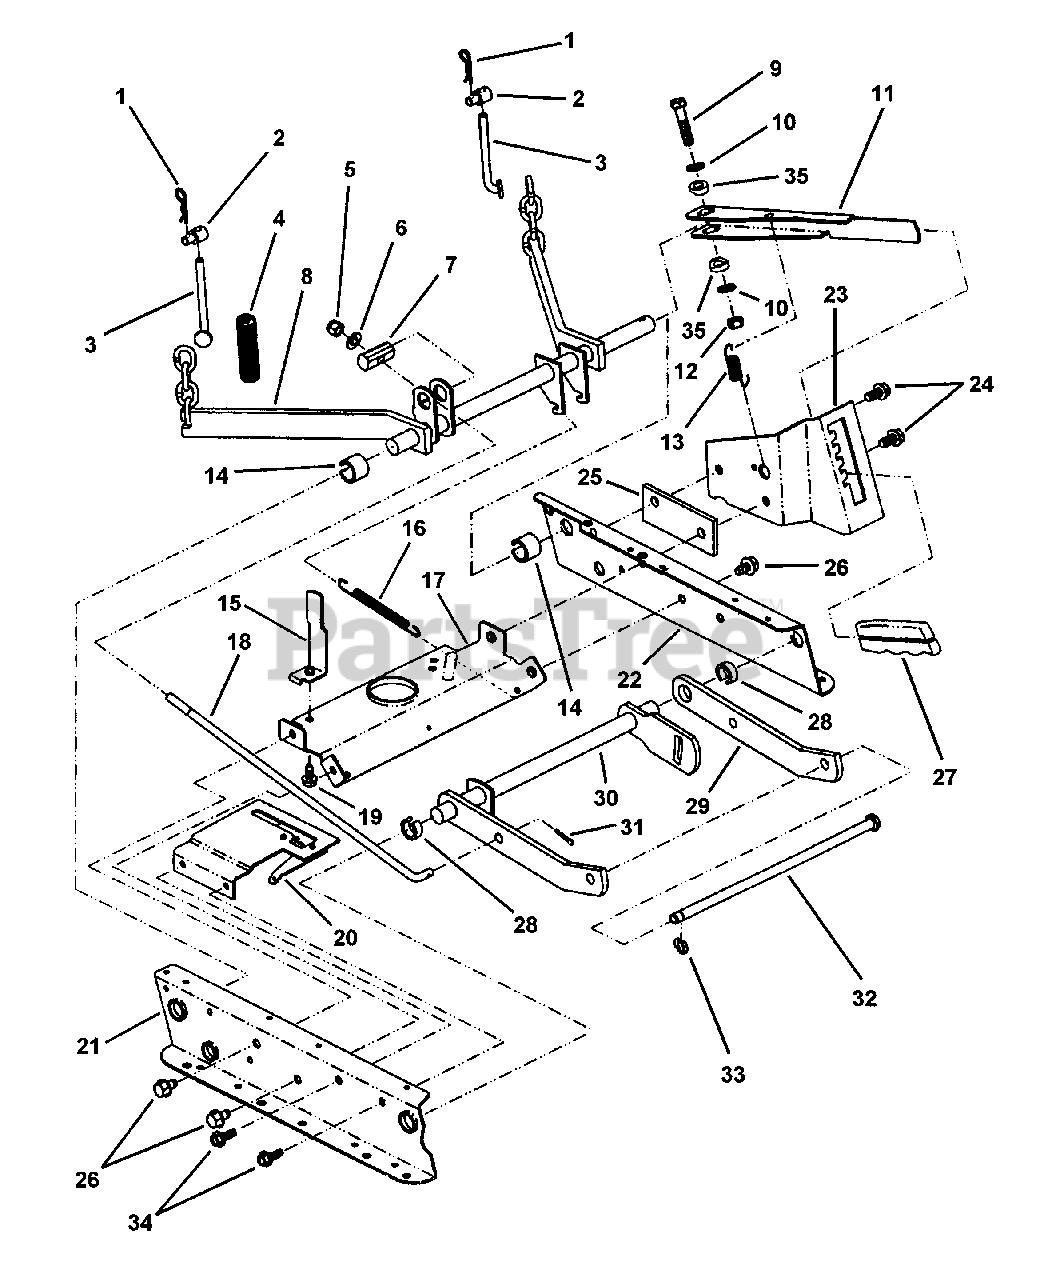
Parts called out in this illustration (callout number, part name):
1	HAIRPIN, 3/32" X 1-1/2"
2	SWIVEL
3	HOOK, Chain
4	COVER, Chain
5	NUT, 3/8-24 Hex Nyloc
6	WASHER, 3/8" Flat
7	PIVOT, Leveling
8	ARM, Rear Lift
9	SCREW, 3/8-24 X 1-3/4" Hex Head Cap Grade 5
10	WASHER, 13/32" Flat
11	LEVER, Height of Cut
12	NUT, 3/8-24 Hex Center Lock
13	SPRING, Lever
14	RING, Blue
15	GUIDE, Belt
16	SPRING, Assist
17	BRACE, Top
18	ROD, Leveling
19	SCREW, 5/16-18 x 5/8" Self-Tap
20	ASSEMBLY, Clutch Plate
21	RAIL, Deck Lift, Right Hand
22	RAIL, Deck Lift, Left Hand
23	DETENT, Height Adjust
24	SCREW, 3/8-16 x 1" Hex Washer Self-Tap
25	DETENT, Spacer
26	SCREW, 3/8-16 x 5/8" Hex Washer Self-Tap
27	GRIP, Height Adjustment Lever
28	RING, Red
29	ARM, Lift
30	ARM, Front Lift (Weldment)
31	PIN, 1/8 x 3/4" Cotter
32	ROD, Support
33	SNAP RING, 7/16"
34	SCREW, 5/16-18 X 1/2" Hex Washer Self-Tap
35	SPACER, Deck Lift
